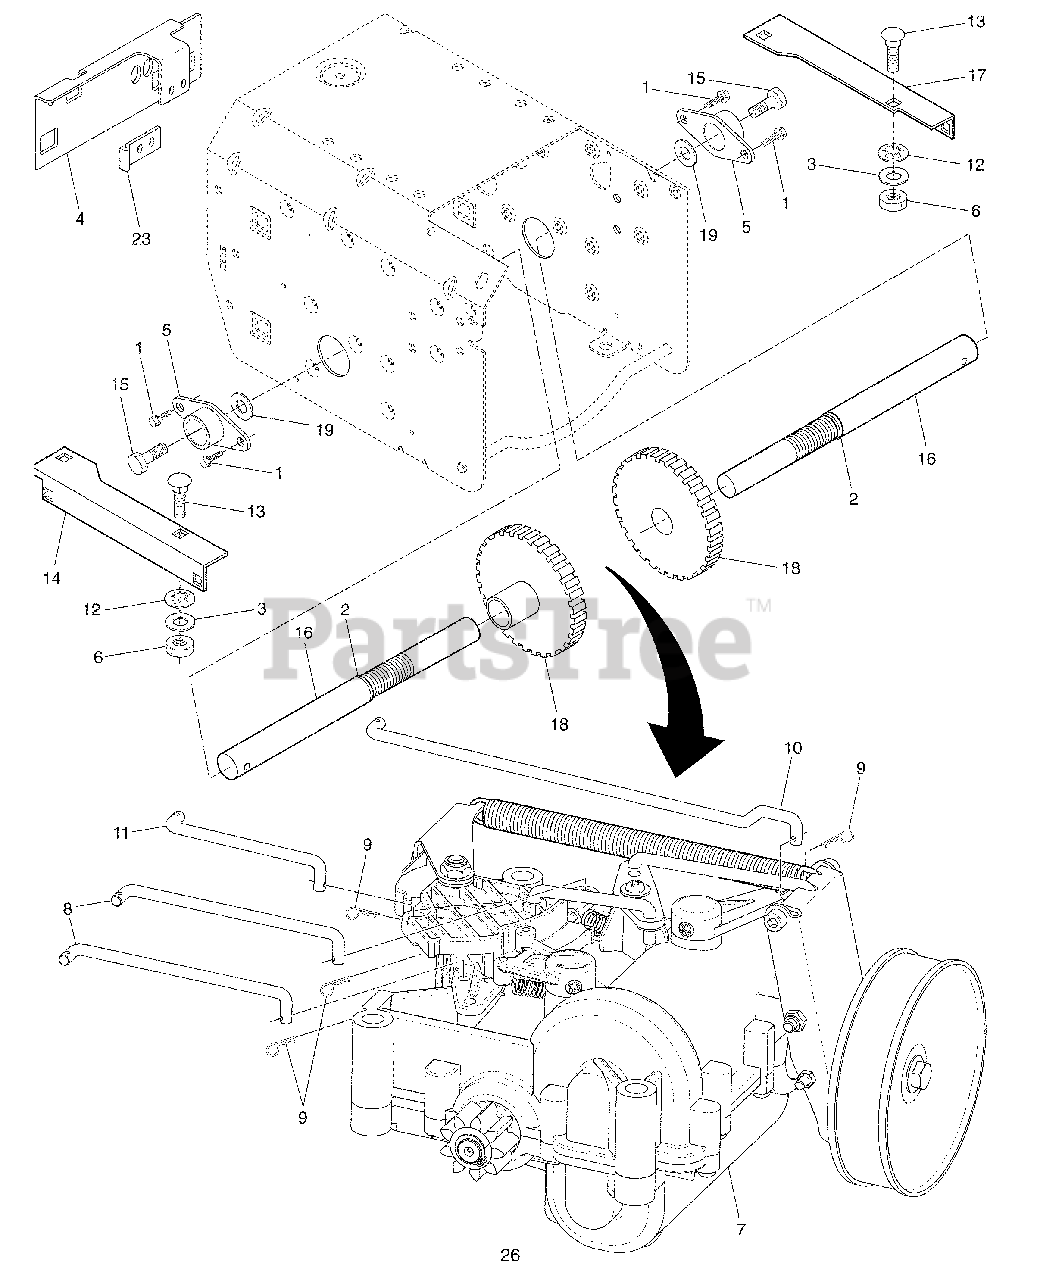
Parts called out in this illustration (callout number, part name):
1	Screw, Hex Head 5/16-18 x 3/4
2	Ring, Retaining
3	Washer, Flat
4	Plate, Rod Alignment
5	Bearing, Axle
6	Nut, Hex, Centerlock 3/8-16
7	Transmission Assembly
8	Control Rod, Steering
9	Retainer Clip
10	Control Rod, Clutch
11	Control Rod, Speed
13	Bolt, Carriage 3/8-16 x 3-1/4
14	Bracket, GT Transmission, RH
15	Screw, Hex Head
16	Shaft, Axle
17	Bracket, GT Transmission, LH
18	Gear, Axle
19	Washer, Flat
23	Spring, Leaf
